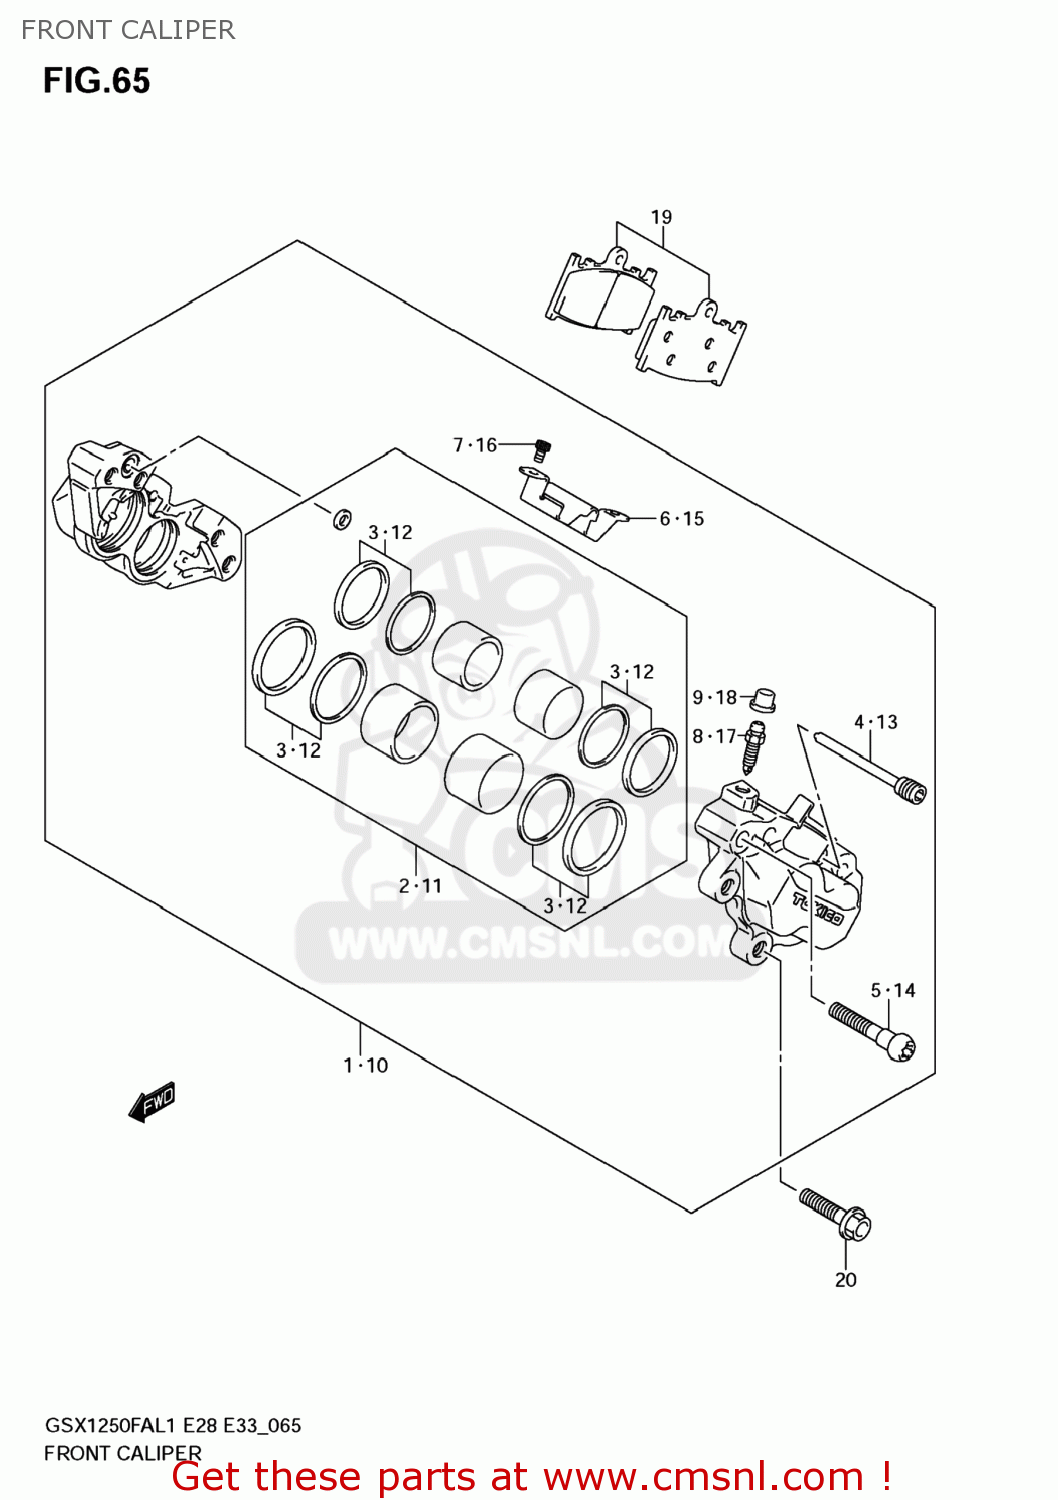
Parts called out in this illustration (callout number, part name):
1	CALIPER ASSY,FR,R
2	PISTON SET
3	SEAL SET,PISTON
4	PIN,PAD
5	BOLT
6	COVER,CALIPER DUST
7	SCREW
8	BLEEDER
9	CAP,BLEEDER PLUG
10	CALIPER ASSY,FR,L
11	PISTON SET
12	SEAL SET,PISTON
13	PIN,PAD
14	BOLT
15	COVER,CALIPER DUST
16	SCREW
17	BLEEDER
18	CAP,BLEEDER PLUG
19	PAD SET (NAS)
20	BOLT(8X28)
